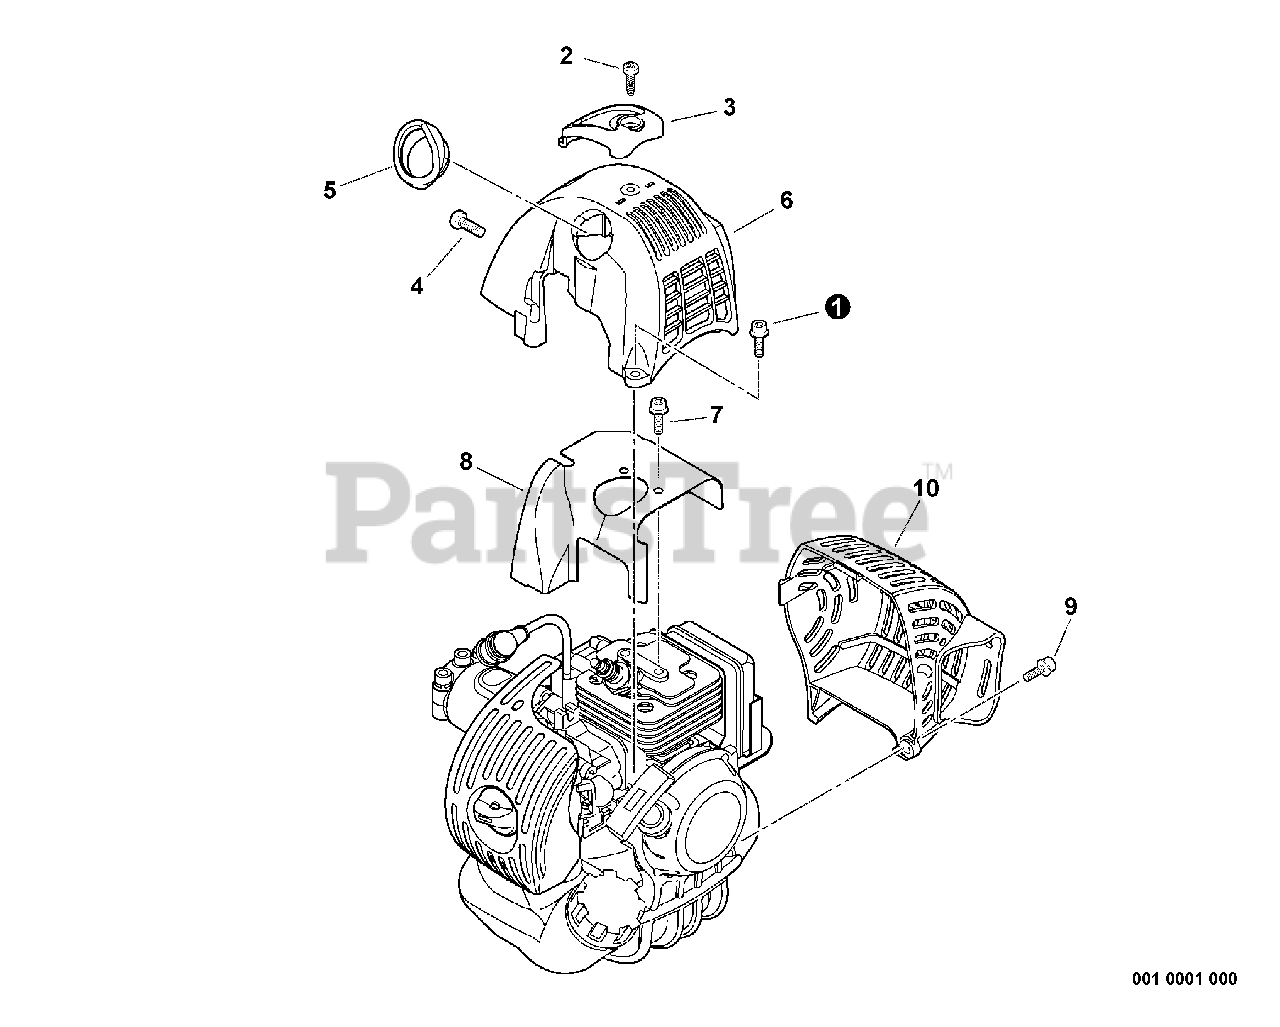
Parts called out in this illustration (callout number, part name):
1	SCREW - 5X14
2	SCREW - 5X16
3	GUARD - TOP
4	SCREW - 5X12
5	SEAL, DUST
6	COVER, ENGINE
7	SCREW - 5X8
8	SHIELD, CYLINDER
9	SCREW - 5X14
10	COVER, EXHAUST
